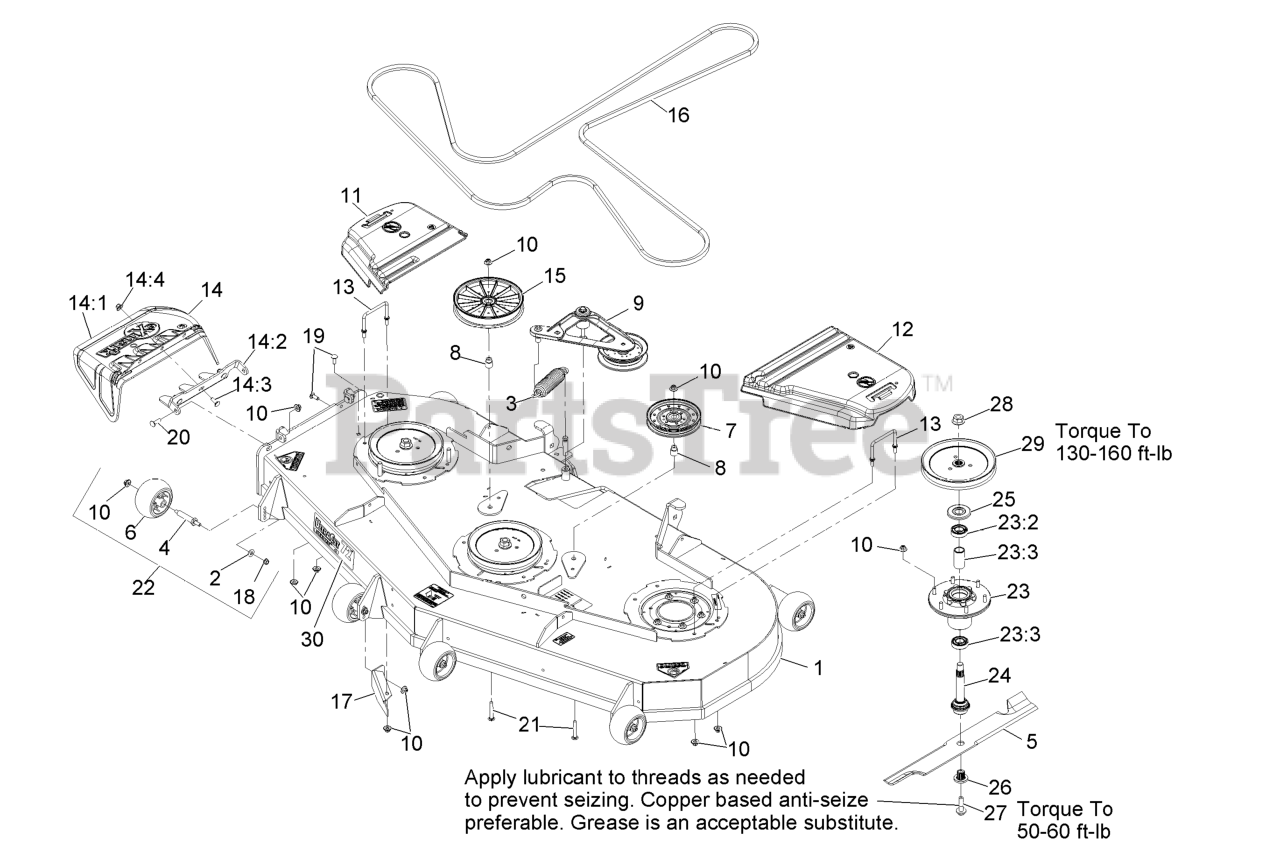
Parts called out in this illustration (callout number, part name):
1	ASM,DECK W/DECALS 724
2	WASHER-BELLEVILLE
6	ROLLER-SCALP, ANTI
8	BUSHING-IDLER
9	DECK IDLER ASM
10	Nut-Nyloc 3/8-16 Flg
11	COVER-BELT, RH
12	COVER-BELT, LH
13	WIREFORM-COVER
14	ASM,DISCHARGE CHUTE
14:1	CHUTE,DISCHARGE
14:2	BRACKET,DISCHARGE CHUTE
14:3	SCREW-CARR
14:4	Nut-Nyloc 3/8-16 Flg
15	PULLEY,IDLER 8"FLAT
16	BELT-V
17	BAFFLE,DISCHARGE 726
18	NUT-HHF, WHIZ
19	SCREW-CARR
20	Bolt-Carriage 3/8-16 X 1 1/4
21	SCREW-CARR
23	ASM-CUTTER HSG WITH BEARINGS
23:2	BEARING-BALL
23:3	SPACER-BEARING
24	ASM-SPINDLE AND SEAL
25	GUARD,BEARING TOP .989
26	BUSHING,SPLINED
27	SCREW,SEMS 1/2-20 X 2.19
28	NUT-FLANGE
29	SHEAVE,BLADE DRIVE 8.74
30	DECAL,ULTRACUT 72 SERIES
